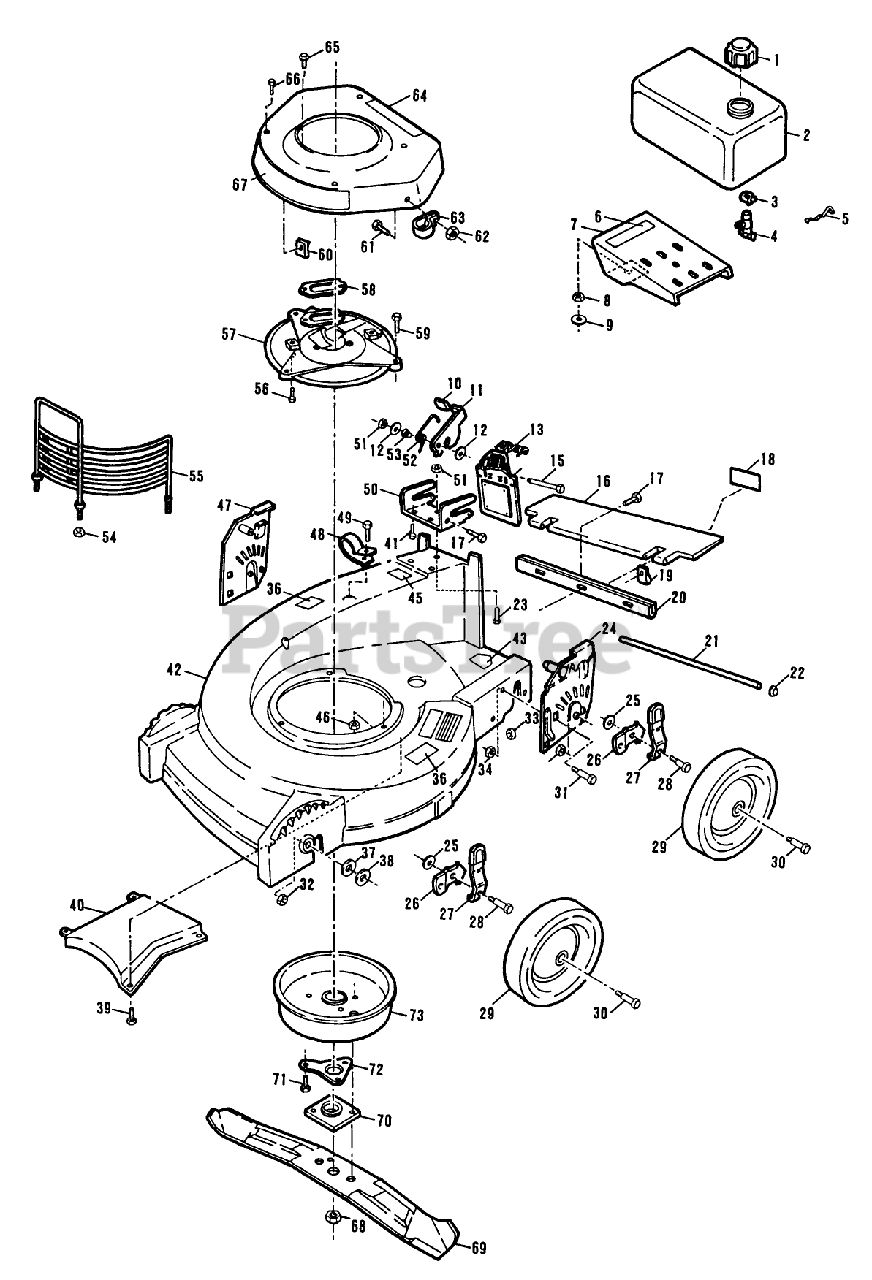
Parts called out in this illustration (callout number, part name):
1	FUEL CAP & INSERT
3	CLAMP - HOSE S
4	VALVE&SCREEN SM
5	SPRING
7	BRACKET - TANK
8	LOCKNUT E
9	WASHER
10	KNOB (S&R)
13	SPRING ASOC
15	ROD (RB&W)
16	T/SHIELD SM&P
23	SCREW
25	WASHER
28	BOLT
29	WHL & TIRE AY
30	BOLT-SHOULDER
32	LOCKNUT
33	LOCKNUT E
34	NUT-LOCK F
35	SPRING ARM ASM
37	WASHER
38	WASHER
40	BAFFLE CHUTE PL
41	SCREW HEX WASHER
46	NUT-LOCK F
49	SCREW LAWRENCE
51	LOCKNUT E
52	SPRING
54	NUT-LOCK F
56	SCREW V
57	M/PLATE
59	SCREW-HH
60	PUSHNUT F
62	LOCKNUT E
65	SCREW SEMS SM
66	SCREW - SELF TAPPING
68	NUT-BLADE
70	PLATE AND COLLAR ASM
71	SCREW
72	SUPPORT F
73	MUFFLER COVER F
